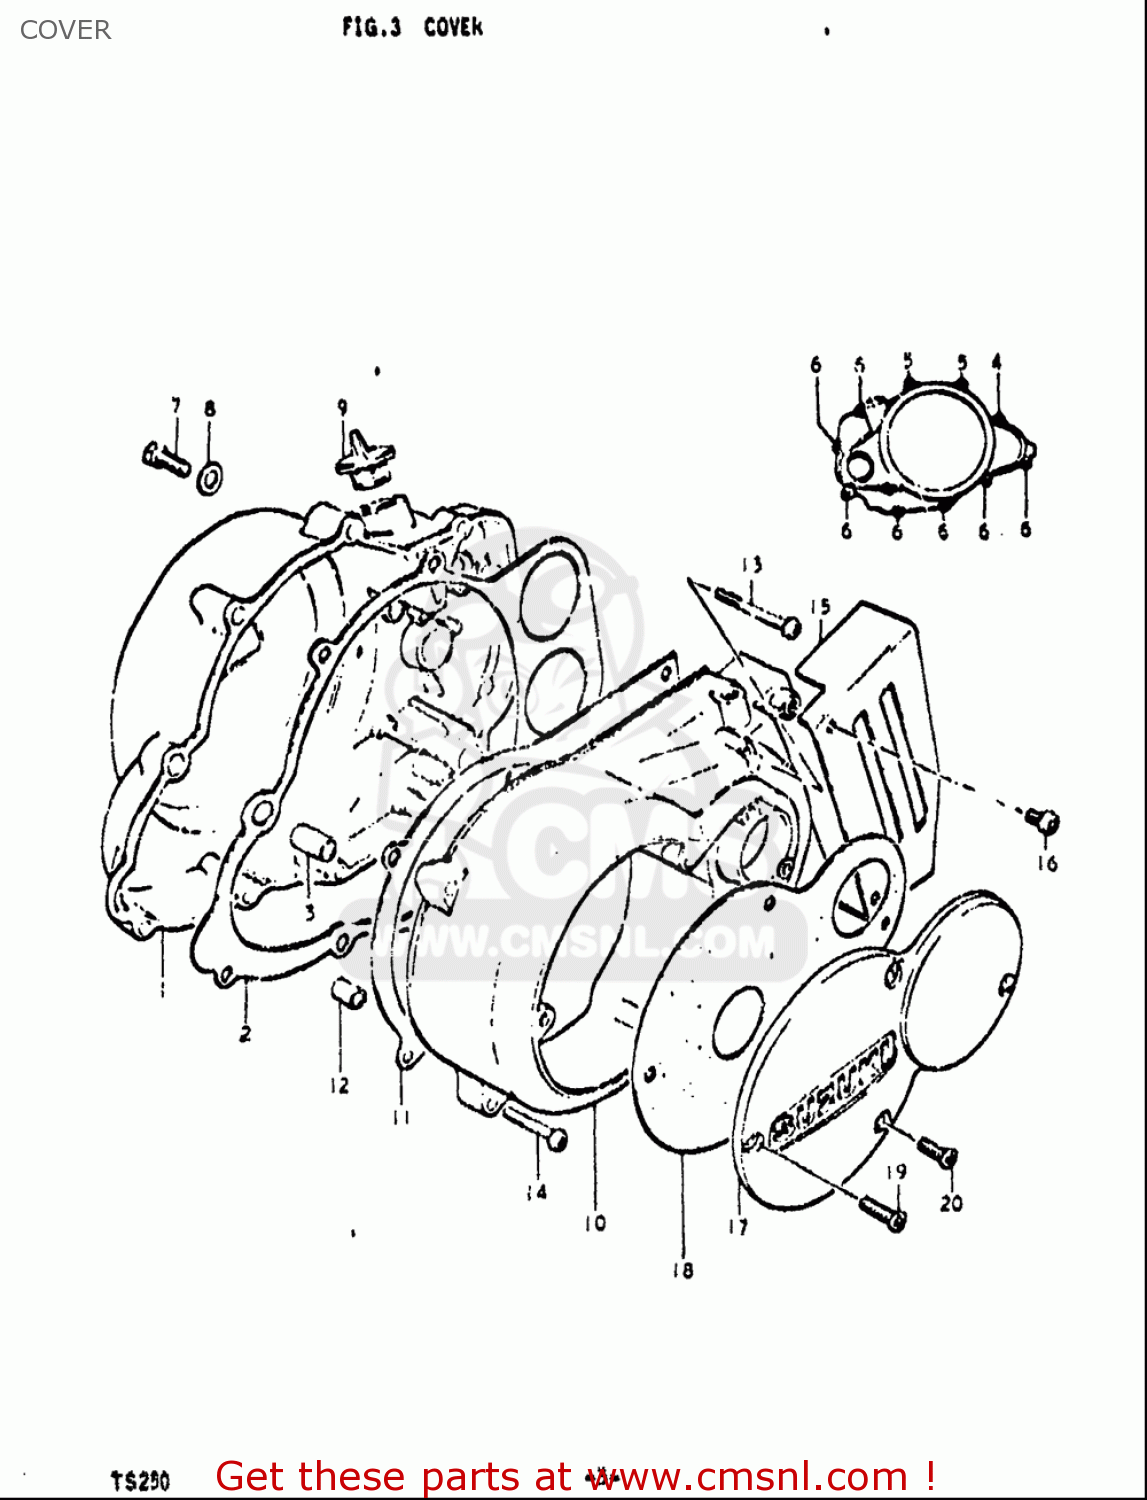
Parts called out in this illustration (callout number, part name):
2	GASKET,CLUTCH COVER (NAS)
3	PIN
4	SCREW
5	SCREW
6	SCREW
7	SCREW(6X10)
8	GASKET(6.2X11X1) (NAS)
9	PLUG
10	COVER,MAGNETO
11	GASKET,MAGNETO COVER (NAS)
12	PIN
13	SCREW
14	SCREW
16	SCREW
18	GASKET,MAGNETO INSPECTION (NAS)
19	SCREW
20	SCREW
